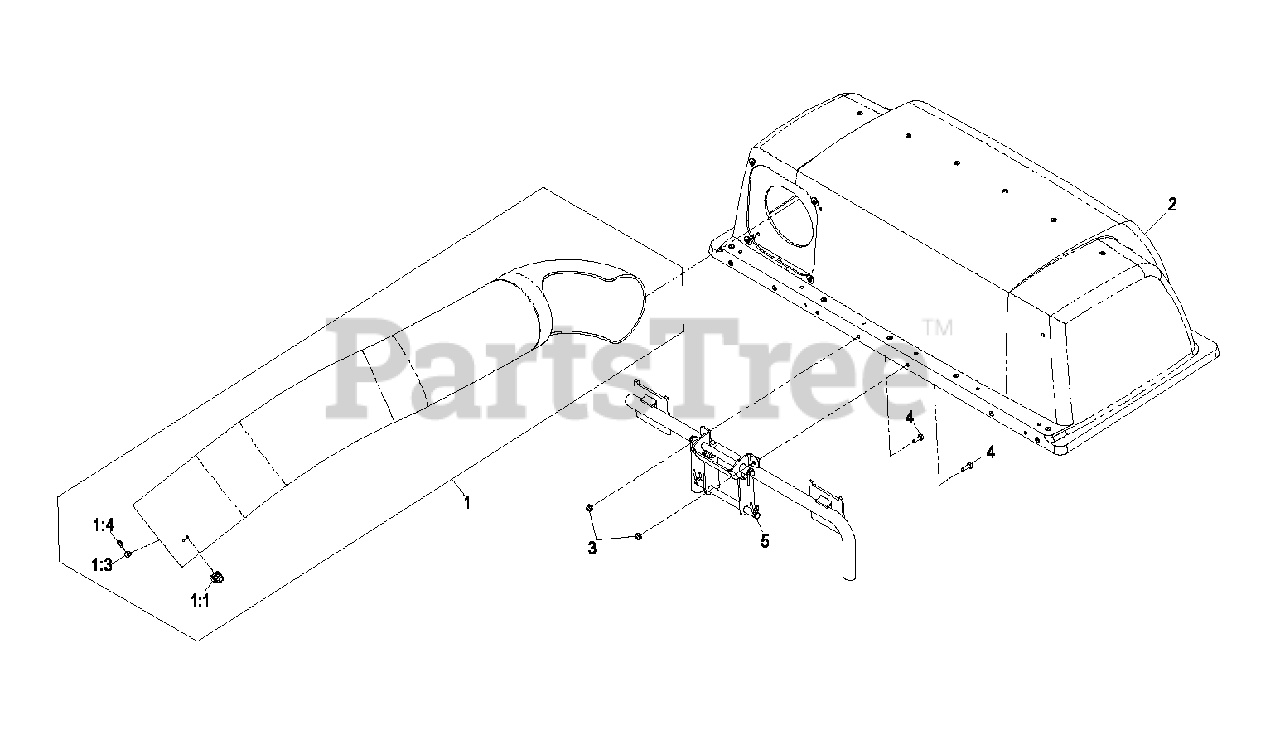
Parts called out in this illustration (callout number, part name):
1	UPPER TUBE ASM
1:1	LATCH-KEEPER
1:3	WASHER-FLAT
1:4	SCREW-PPH
4	SCREW-HH
5	BAGGER MOUNT ASM
